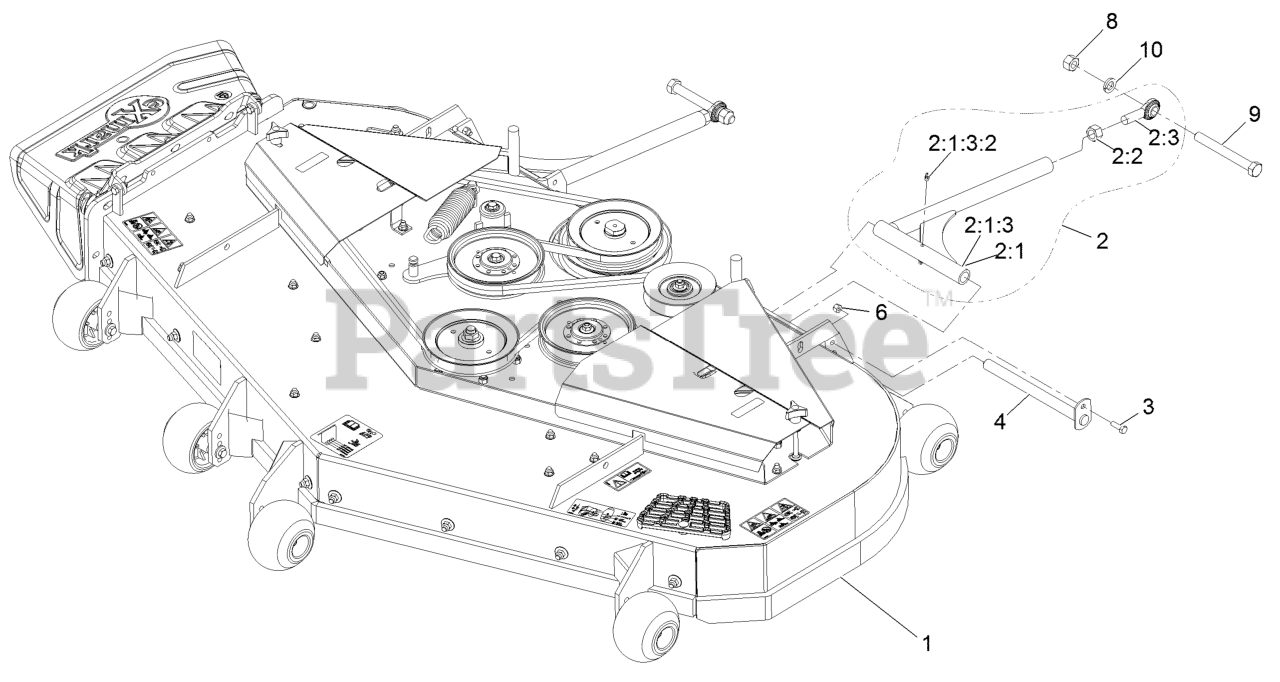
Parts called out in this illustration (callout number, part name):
1	ASM-Deck Complete 605
2	ASM,DECK STRUT XS 60
2:1	STRUT-DECK
2:1:3	Tube And Zerk ASM
2:2	NUT-HEX
2:3	BALLJOINT-SPHERICAL
3	SCREW-HH
4	PIN-STRUT
6	NUT-LOCK, NI
8	NUT-HEX
9	SCREW-HH
10	WASHER-LOCK
